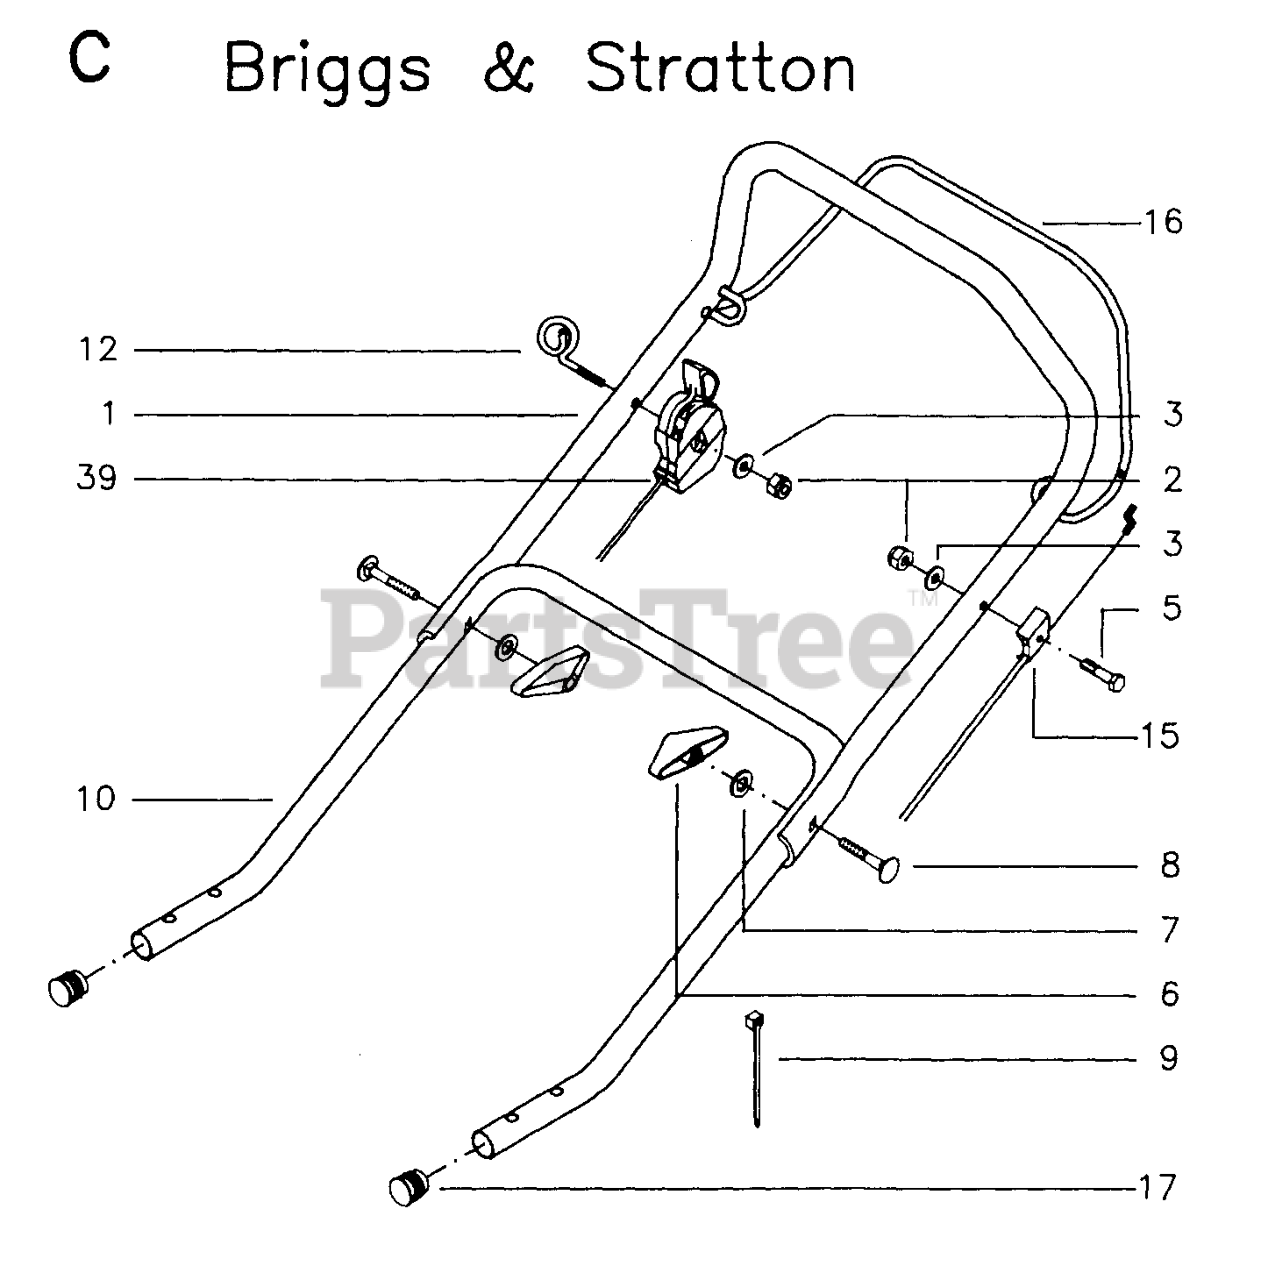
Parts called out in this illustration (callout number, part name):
2	LOCKNUT M6
5	BOLT FLANGE
6	WINGNUT
15	REPL BY 532 85 16-72
39	THROTTLE TRIGGER
